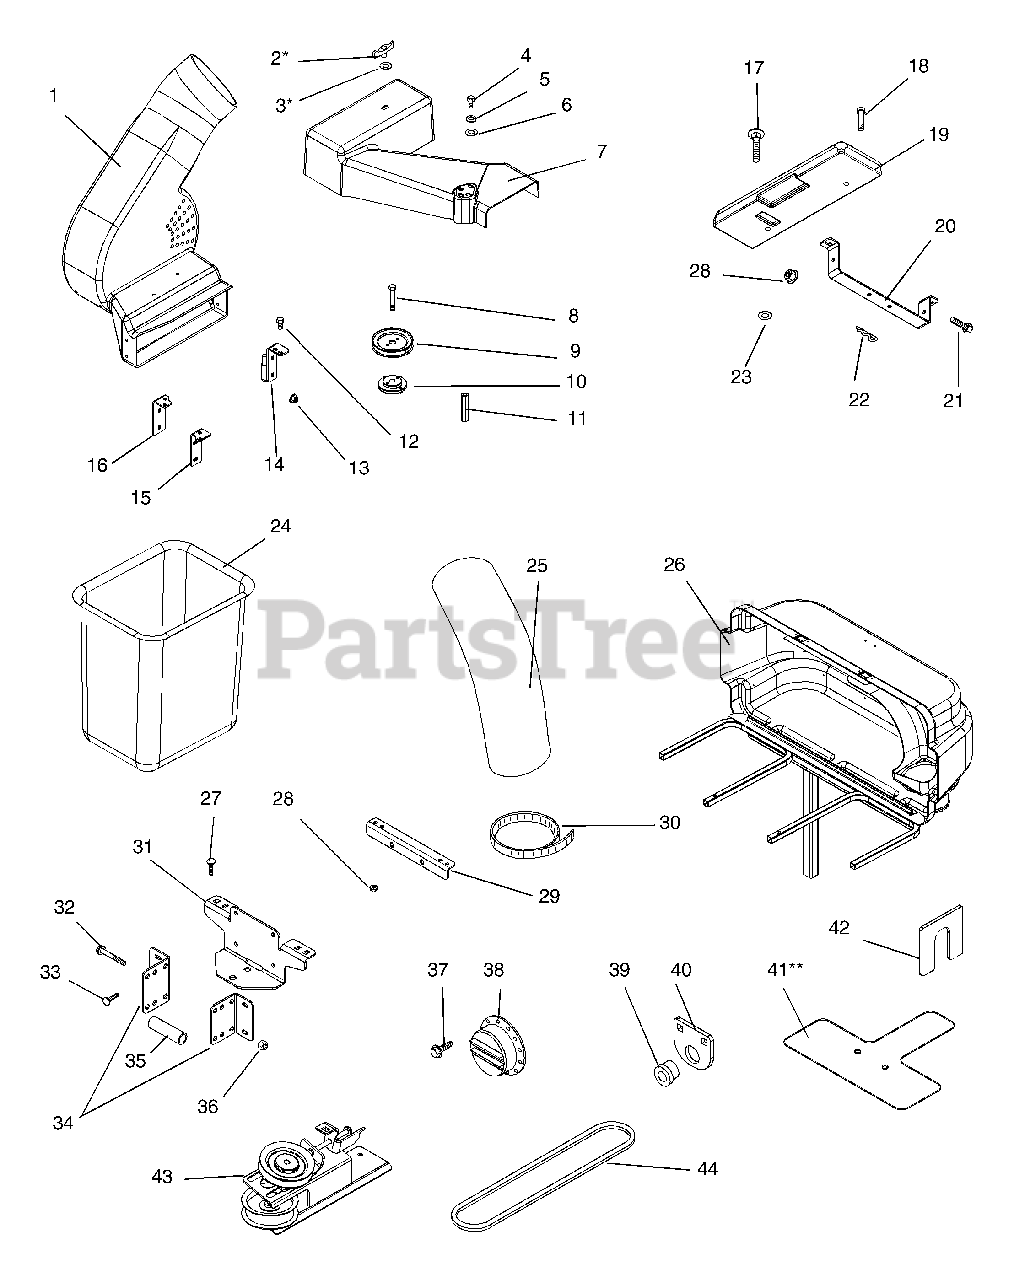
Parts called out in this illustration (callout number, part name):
1	Blower Assembly
2	Wing Knob
3	3/8" x 1-1/2" Washer
4	3/8" x 3/4' Hex Bolt
5	3/8" Lock Washer
6	7/16" x 1" Flat Washer
7	Belt Cover
8	3/8" x 1-3/4" Hex Bolt
9	3-Inch Sheave (40- and 44-Inch Mower Decks)
9	4-Inch Sheave (48- and 52-Inch Mower Decks)
10	Sheave Adapter
12	1/4" x 3/4" Hex Bolt
13	1/4" Top Lock Flange Nut
14	Rear Mount Weldment Bracket
15	Front Bracket
16	Front Mount Weldment Bracket
17	3/8" x 1" Round Head Square Neck Bolt
18	Clevis Pin
19	Counterweight
20	Counterweight Bracket
21	3/8" x 1" Hex Bolt
22	Hair Pin
23	1/2" x 1-5/8" Flat Washer
24	Grass Bagger Basket
26	Cover Assembly
27	3/8" x 2-1/2" Round Head Square Bolt
28	3/8" Top Lock Flange Nut
29	Angle Bracket
30	Hose Clamp
31	Trailer Hitch
32	1/2" x 3" Hex Bolt
33	3/8" x 1-1/4" Round Head Square Neck Bolt
34	Bagger Mount Bracket
35	Pivot Spacer
36	1/2" Top Lock Flange Nut
37	Self-Tapping Screw
38	Exhaust Deflector
39	Flange Bushing
40	Rear Pivot Bracket
41	Finger Guard
42	Lift Plate
43	Idler Assembly
44	40- and 44-Inch V-Belt
44	48- and 52-Inch V-Belt
